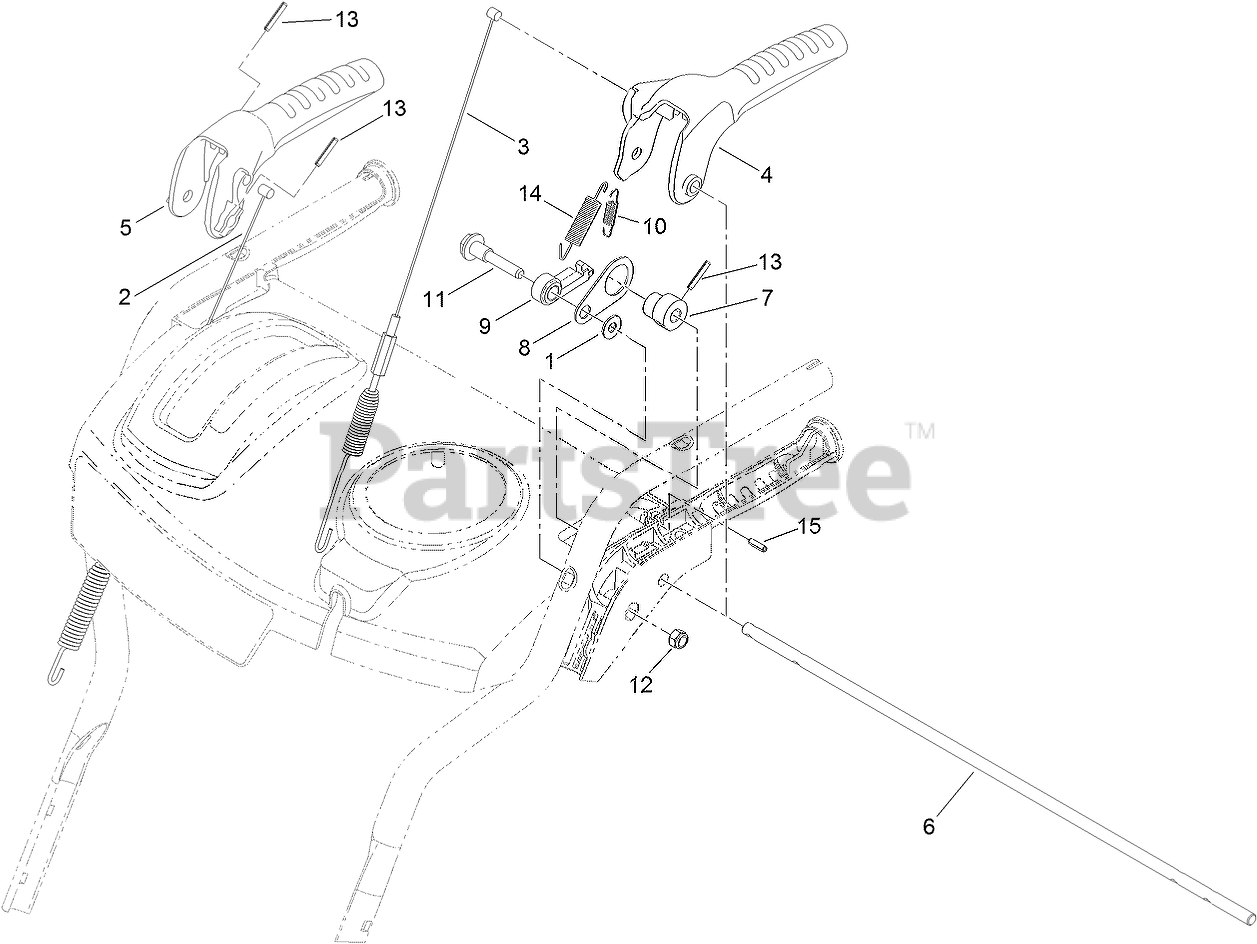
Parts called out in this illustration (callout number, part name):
1	WASHER-FLAT
2	CABLE-AUGER
3	CABLE-TRACTION
4	HANDLE-CONTROL, TRACTION
5	HANDLE-CONTROL, AUGER
6	ROD-LOCKOUT
7	CAM-LOCKOUT
8	LINK-LOCKOUT
9	LATCH-LOCKOUT
10	SPRING-LOCKOUT
11	SCREW-SHOULDER
12	NUT-LOCK, NI
13	PIN-SPRING
14	SPRING-RETURN, TRACTION LEVER
15	PIN-ROLL, SLOTTED
